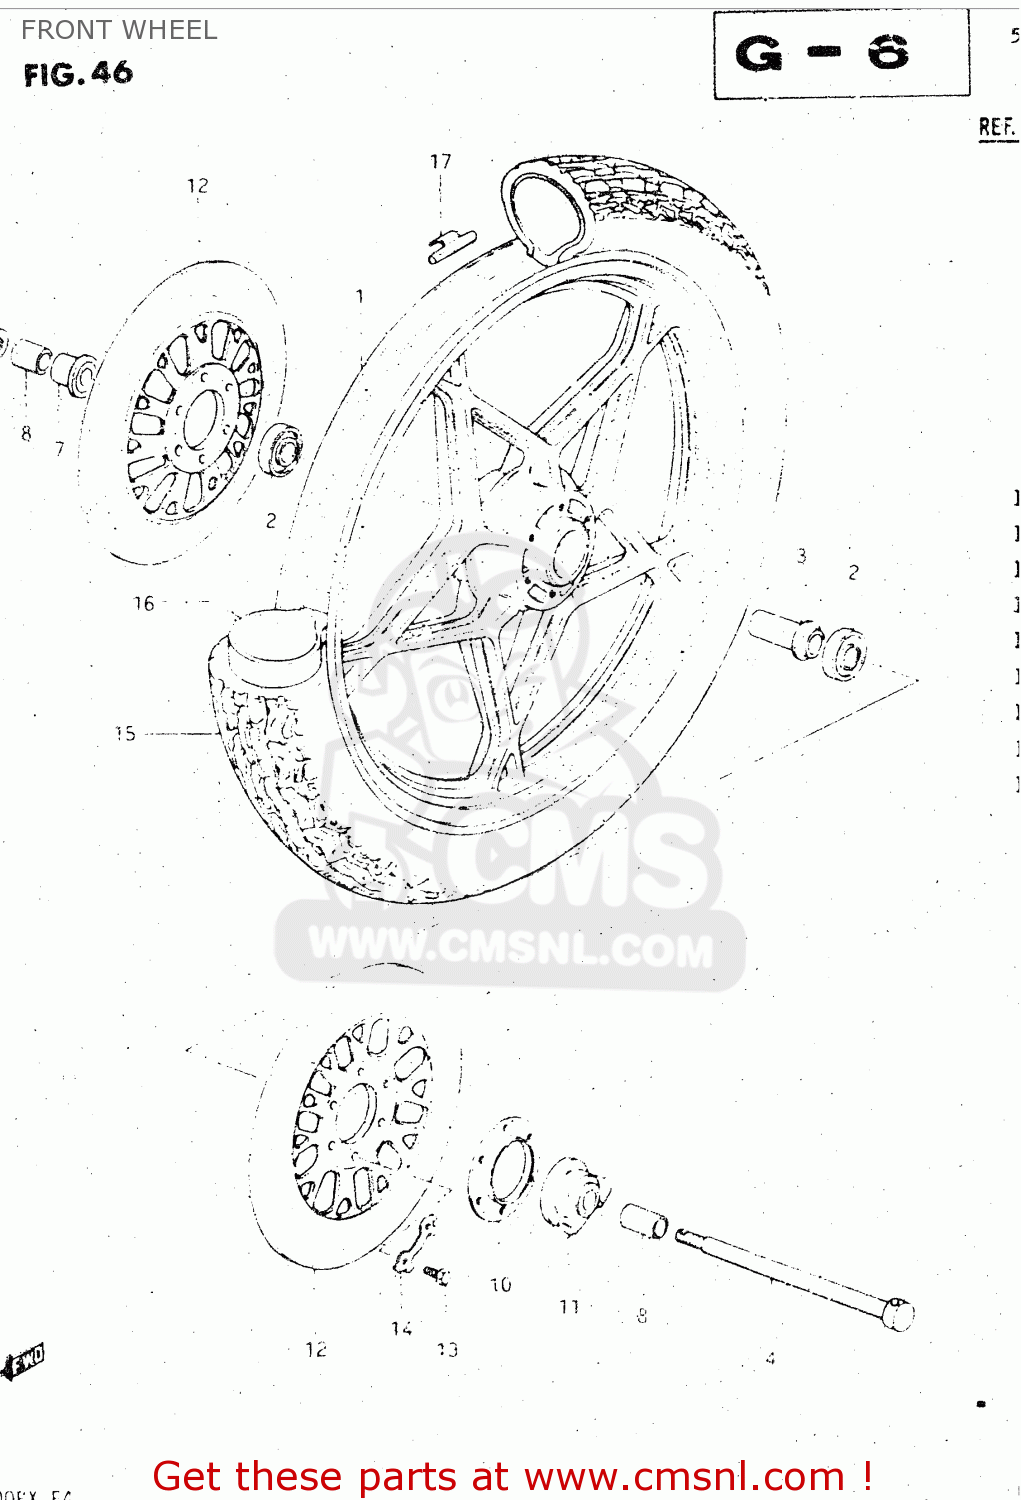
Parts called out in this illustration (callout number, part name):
1	WHEEL, FRONT (19X1.85) (GRAY)
2	BEARING
3	SPACER,FR HUB BEARING
4	AXLE,FRONT
5	NUT 12MM
6	COTTER PIN
7	SPACER,FR HUB BEARING,R
8	SPACER(15X22X30)
9	WASHER
10	DUST SEAL,SPEEDOMETER GEAR BOX
11	BOX ASSEMBLY,SPEEDOMETER GEAR
12	DISC,FR BRAKE
13	BOLT(8X25)
14	WASHER
15	TIRE,FRONT
16	TUBE,INNER
17	BALANCER,WHEEL
